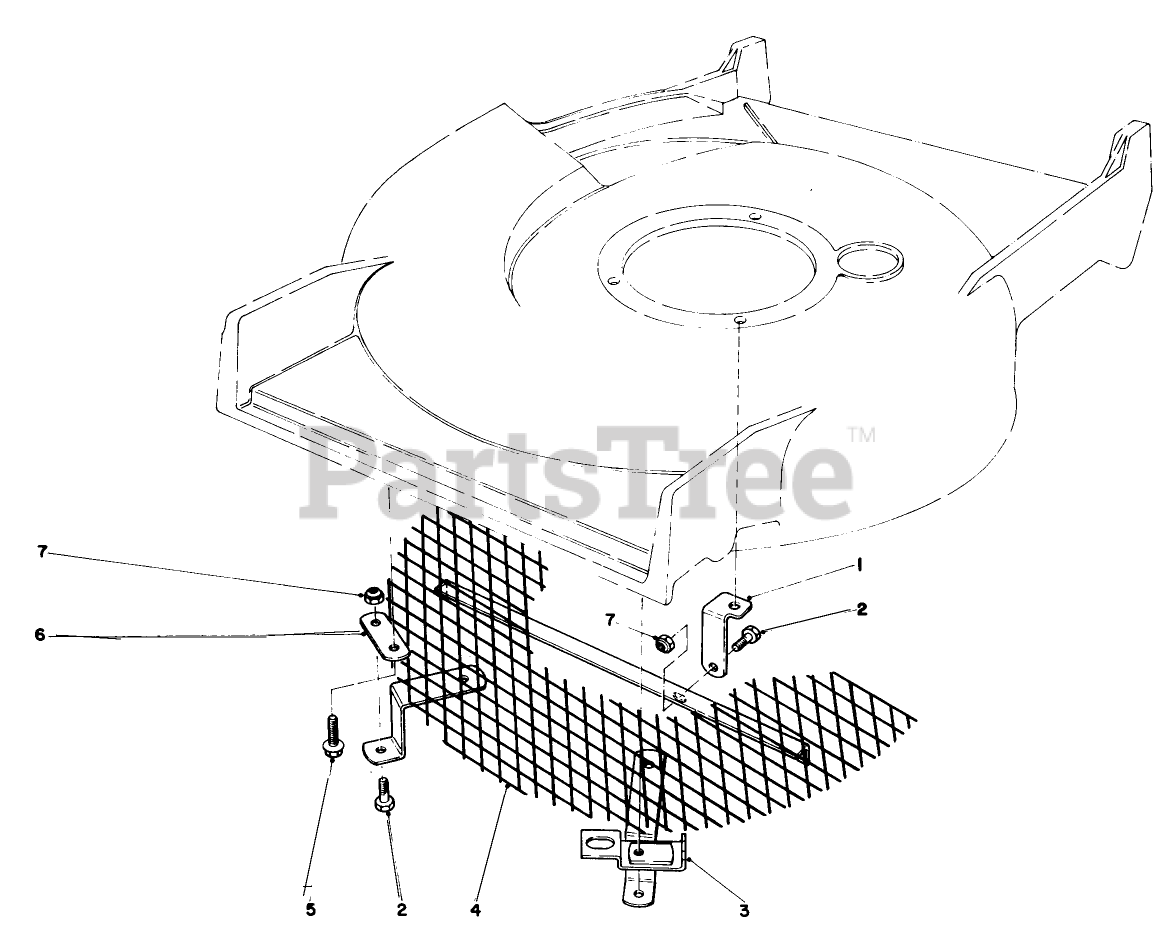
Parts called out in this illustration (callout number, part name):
1	Support Bracket
2	SCREW-HH
3	MTG. BRACKET W.A.
4	Screen
5	SCREW-HWHTF
6	ANCHOR
7	NUT-LOCK, NI
